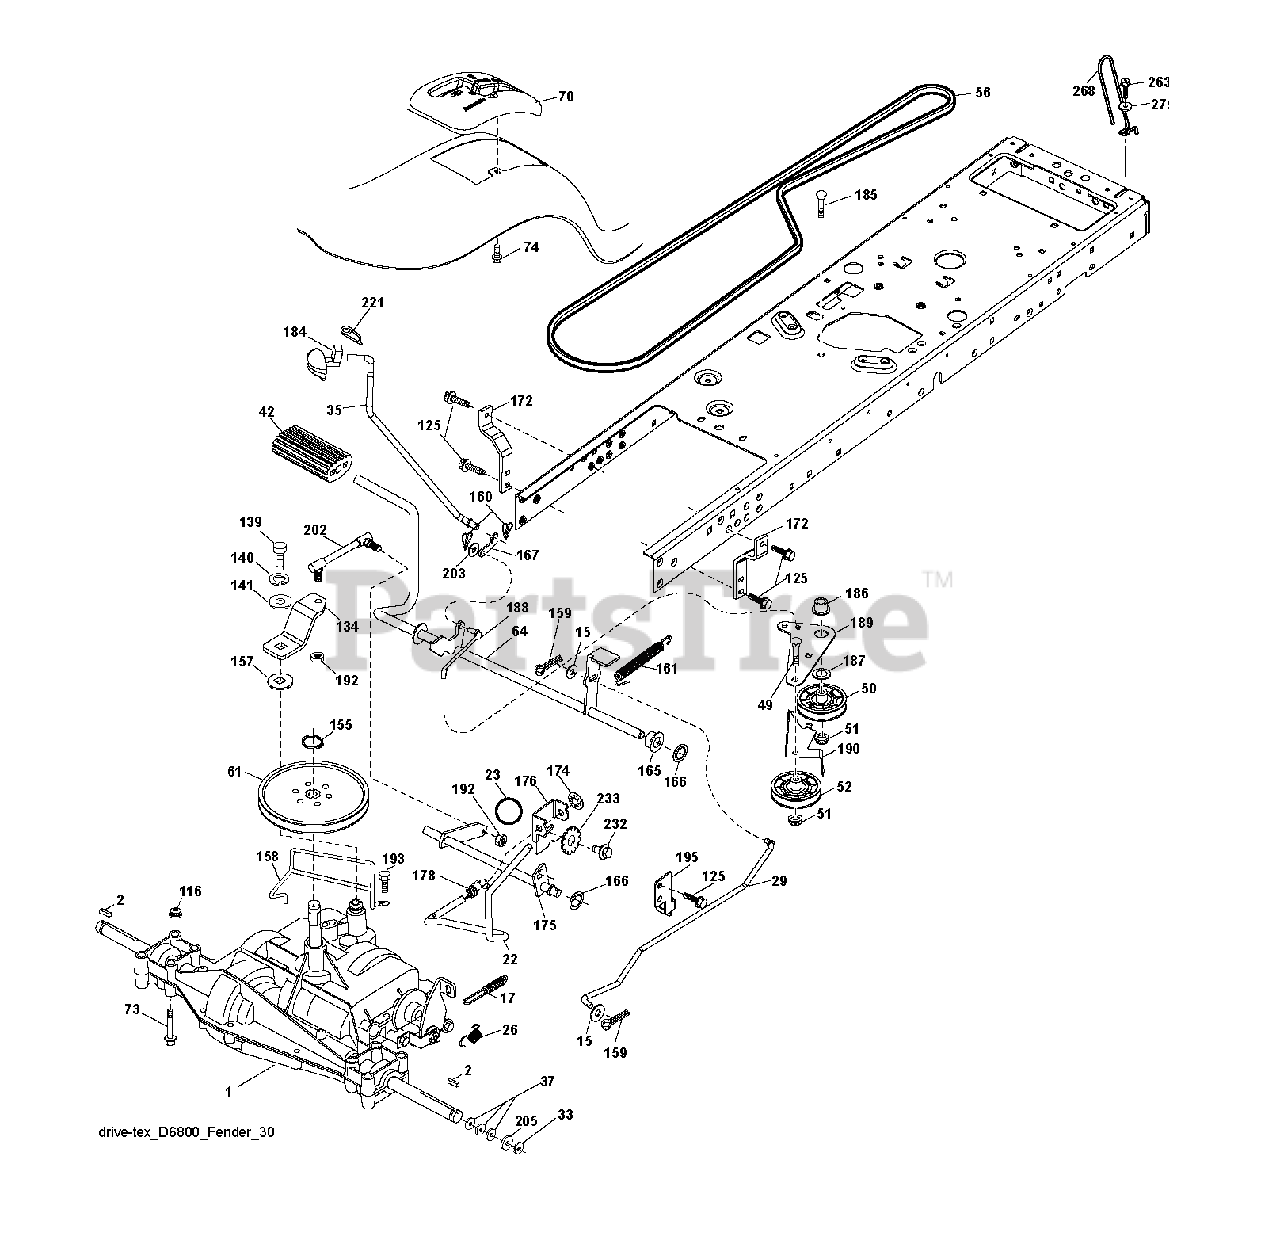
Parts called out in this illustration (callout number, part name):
2	SQUARE KEY
17	SPRING.BRAKE.PEERLESS.TEX
22	ROD.SHIFT.FENDER.TLT.2006
23	KNOB.DUCKHEAD.1/2
26	SPRING.BRAKE.RTN.GR.DR
29	ROD.BRAKE.PEERLESS
33	E-RING LT
35	ROD, BRAKE, PARK
42	PEDAL COVER T
49	BOLT
50	IDLER.FLAT.910.OFFSET
51	NUT LOCK FLG 3/8-16 UNC
52	IDLER.V-GROOVE.910.OFFSET
56	V-BELT.TRACTOR.DRIVE.P
64	SHAFT.ASM.PEDAL.BRAKE.
70	CONSOLE.SHIFT.
73	BOLT HEX 5/16-18 GR 5
74	SCREW.HI-LO.CONSOLE
116	NUT LOCK HEX FLANGE 5/16-18
125	SCREW
134	ARM.SHIFT.
139	BOLT 1/4-28X3/4
140	LOCKWASHER
141	WASHER LT
155	RETAINING RING LT
157	WASH-SHFT PLT LT
158	KEEPER.PMS.18/20.D4365
159	COTTER PIN
160	RETAINER CLIP
161	SPRING, RETURN LT
165	BUSHING.SHAFT.BRAKE.HAND
166	NUT.PUSH.625.2006
167	LATCH.BRAKE.SPRING
172	STRAP.TRQ.LH.GEAR.DRIV
174	NUT.PUSH.500.2006
175	SHAFT.ASM.SHIFT.
176	ARM.CLEVIS.ROD.SHIFT
178	SPRING.SHIFT.GT2006
184	HANDLE PARKING BRAKE
186	SPACER.RETAINER
187	WASHER 12/32X2X10GA
188	LINK.CLUTCH.GROUND.DRIVE
189	BELLCRANK.GROUND.DRIVE.TEX.
190	KEEPER.BELLCRANK.DRIVE
192	NUT LOCK CENTER 1/4 -28 FNTHD
193	SCREW 5/16"
195	BRKT.ROD.BRAKE.PEERLES
202	LINK.TRANSAXLE.
203	WASHER
221	RETAINER.SPRING.CLIP.H
232	BOLT FIN HEX 7/16-14 X 1
233	WASHER SERRATED
263	SCREW, 3/8-16X3/4
268	WASHER
